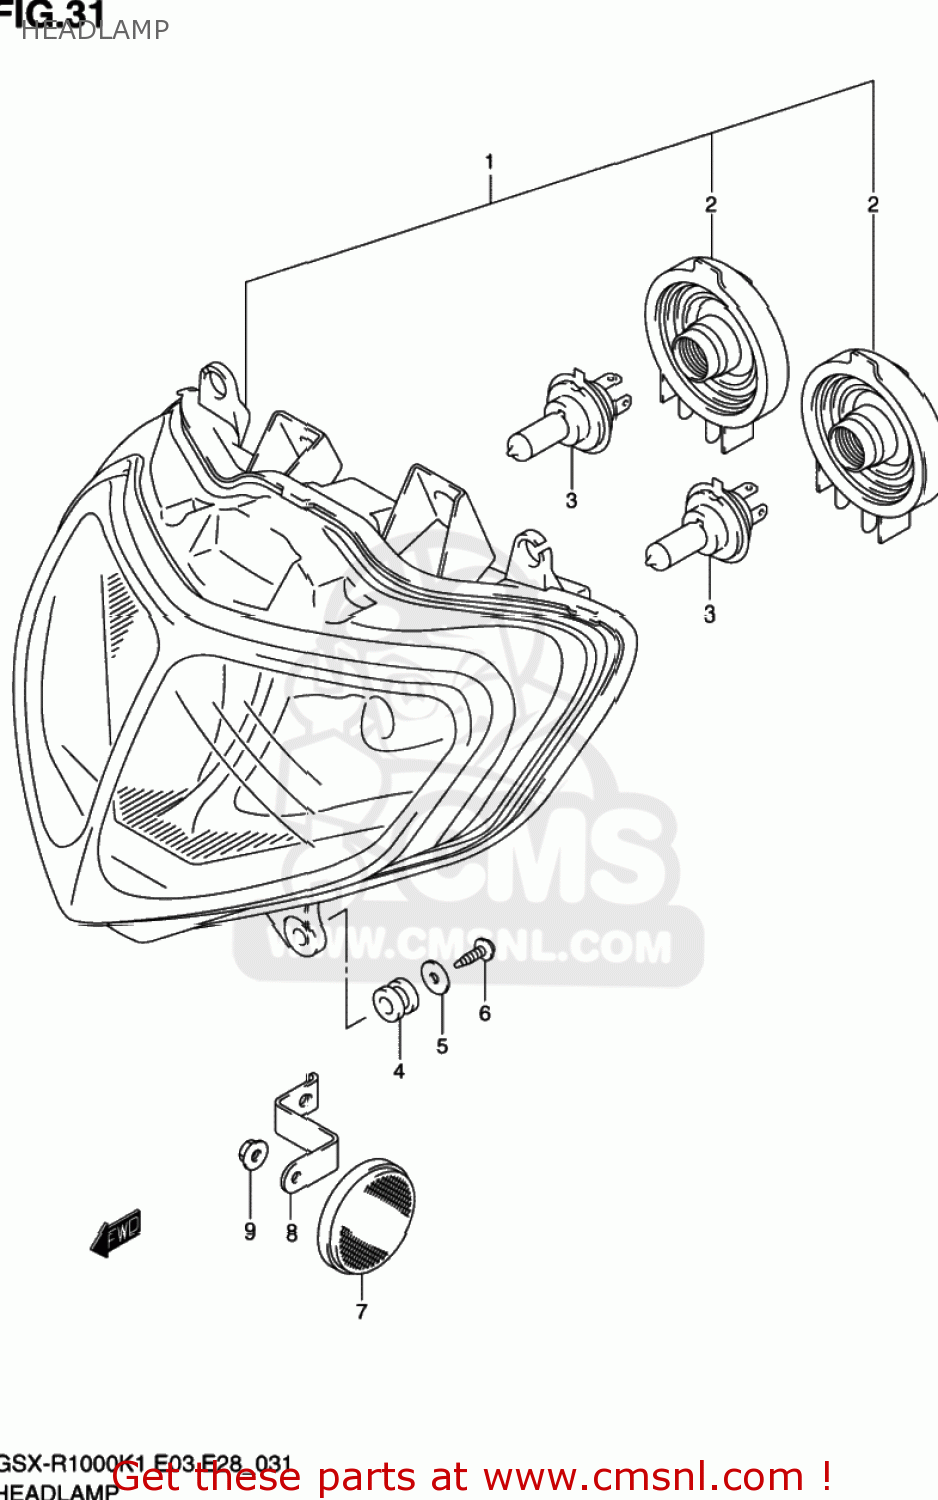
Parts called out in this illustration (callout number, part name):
1	HEADLAMP ASSY
2	COVER,SOCKET
3	BULB(12V60/55W,H4)
4	CUSHION
5	WASHER(5.5X18X1)
6	SCREW
7	REFLECTOR,REFLEX
8	BRACKET,FR SIDE RR
9	NUT
